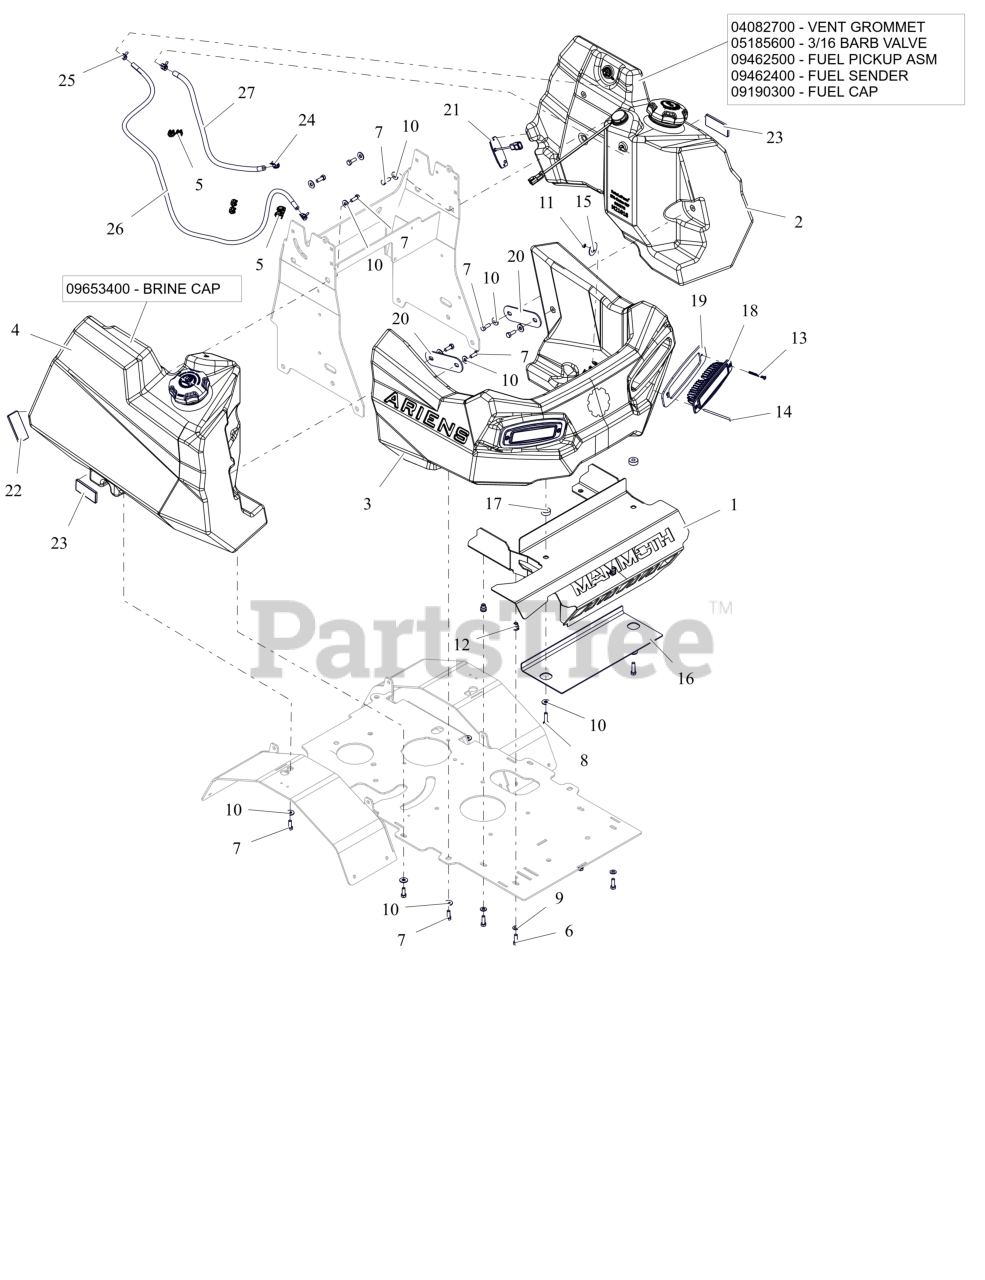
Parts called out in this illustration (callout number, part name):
1	WLDMT, MUFFLER - W/DECAL
2	FUEL TANK - W/DECALS
2	GROMMET, REMOTE VENT NITRILE
2	VALVE, COMBINATION VENT 3/16
2	ASSEMBLY, FUEL PICKUP
2	SENDER, FUEL
2	CAP, FUEL - 3.50 RATCHET INLET VENT
3	BUMPER TANK - W/DECAL
4	BRINE TANK - W/DECALS
4	CAP, BRINE - 3.50"
5	CLIP- FUEL LINE
6	BLT,HEX .31-18X1.00 G5 ZCC
7	BLT, HEX .31-18X.875 G5 ZCC
8	BLT, HEX .31-18X1.25 G5 ZCC
9	WSHR,FLT .344X.688X.065 ZCC
10	WSHR,FLT .375X.875X.083 ZCC
11	NUT-LK-NYL #10-24 G2 ZCC
12	RVT-NUT HEX 5/16-18 LONG
13	SCR-MACHINE- PAN 10-24X2
14	SCR- MACHINE - PAN 10-24X3.25
15	WSHR, CUP #10 ID X 1.5"OD
16	WRAP-MFLR - HEATSHIELD
17	SPCR- EXHAUST
18	LIGHT- BAR W/ DT
19	BEZEL- HEADLAMP
20	COUPLER- PLATE TANKS
21	LIGHT- FLAT LED - WHITE
22	REFLECTOR- RED - ADHESIVE
23	REFLECTOR-AMBER - ADHESIVE
24	CLAMP- HOSE BAND - 1/4"
25	CLAMP- HOSE BAND - 3/16"
26	HOSE- FUEL 3/16 X 48
27	HOSE- FUEL - 1/4-20
